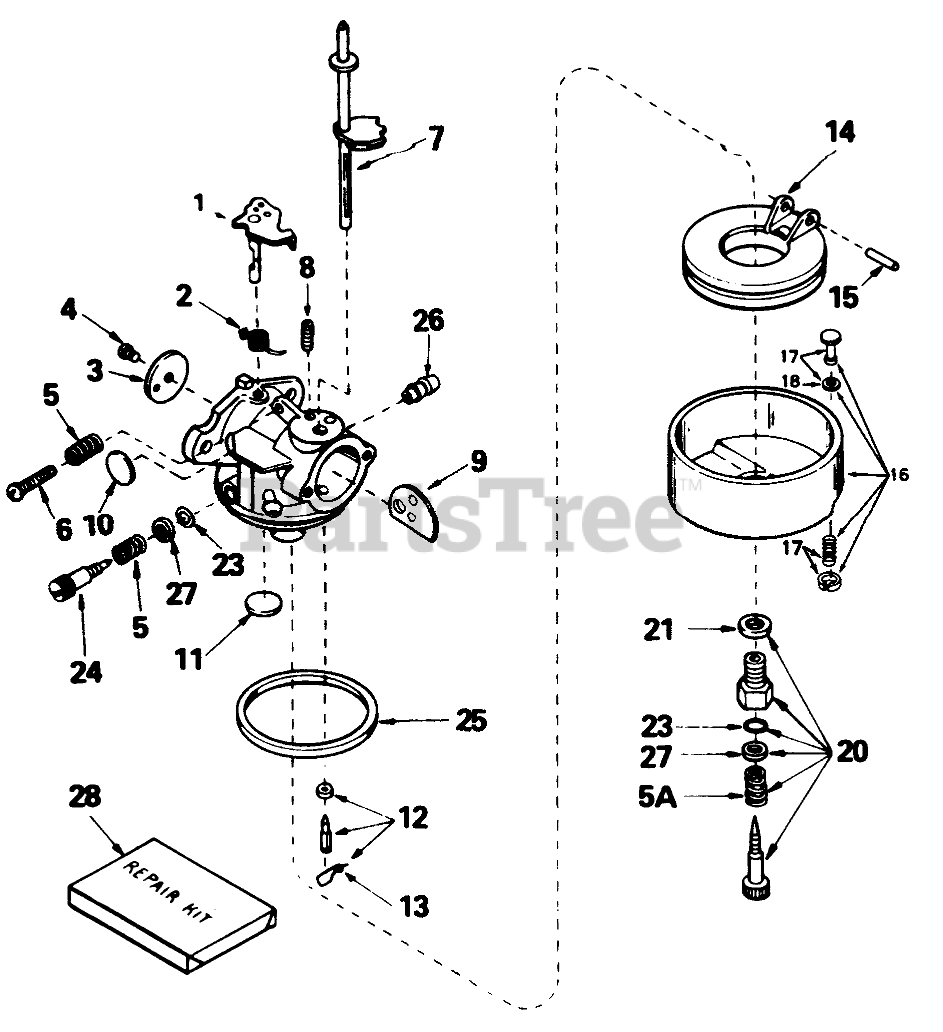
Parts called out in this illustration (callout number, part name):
1	Shaft/Lever-Throttle
2	Spring-Return, Throttle
3	Shutter-Throttle
4	Screw-Shutter
5	Spring-Tension
6	Screw-Throttle Crack Screw / Idle Speed
7	Shaft-Choke
8	Spring-Positioning, Choke
9	Shutter-Choke
10	Plug-Welch, Idle Mixture Well
11	Plug-Welch, Atmospheric Vent
12	Inlet Needle-Seat & Clip (Incl. Ref. #13)
13	Clip-Spring
14	Float
15	Shaft-Float
16	Bowl-Assembly (Incl. Ref. #17 & 18)
17	Drain Assembly-Bowl (Incl. Ref. #18)
18	Gasket-Plunger, Drain
20	Screw Adjustment Assembly (Incl. Ref. #5A, 21, 23, & 27)
21	Washer-Bowl Nut
23	"O"Ring
24	Screw-Idle
25	O Ring-Bowl, Float
26	Fitting-Fuel
28	Kit-Repair
